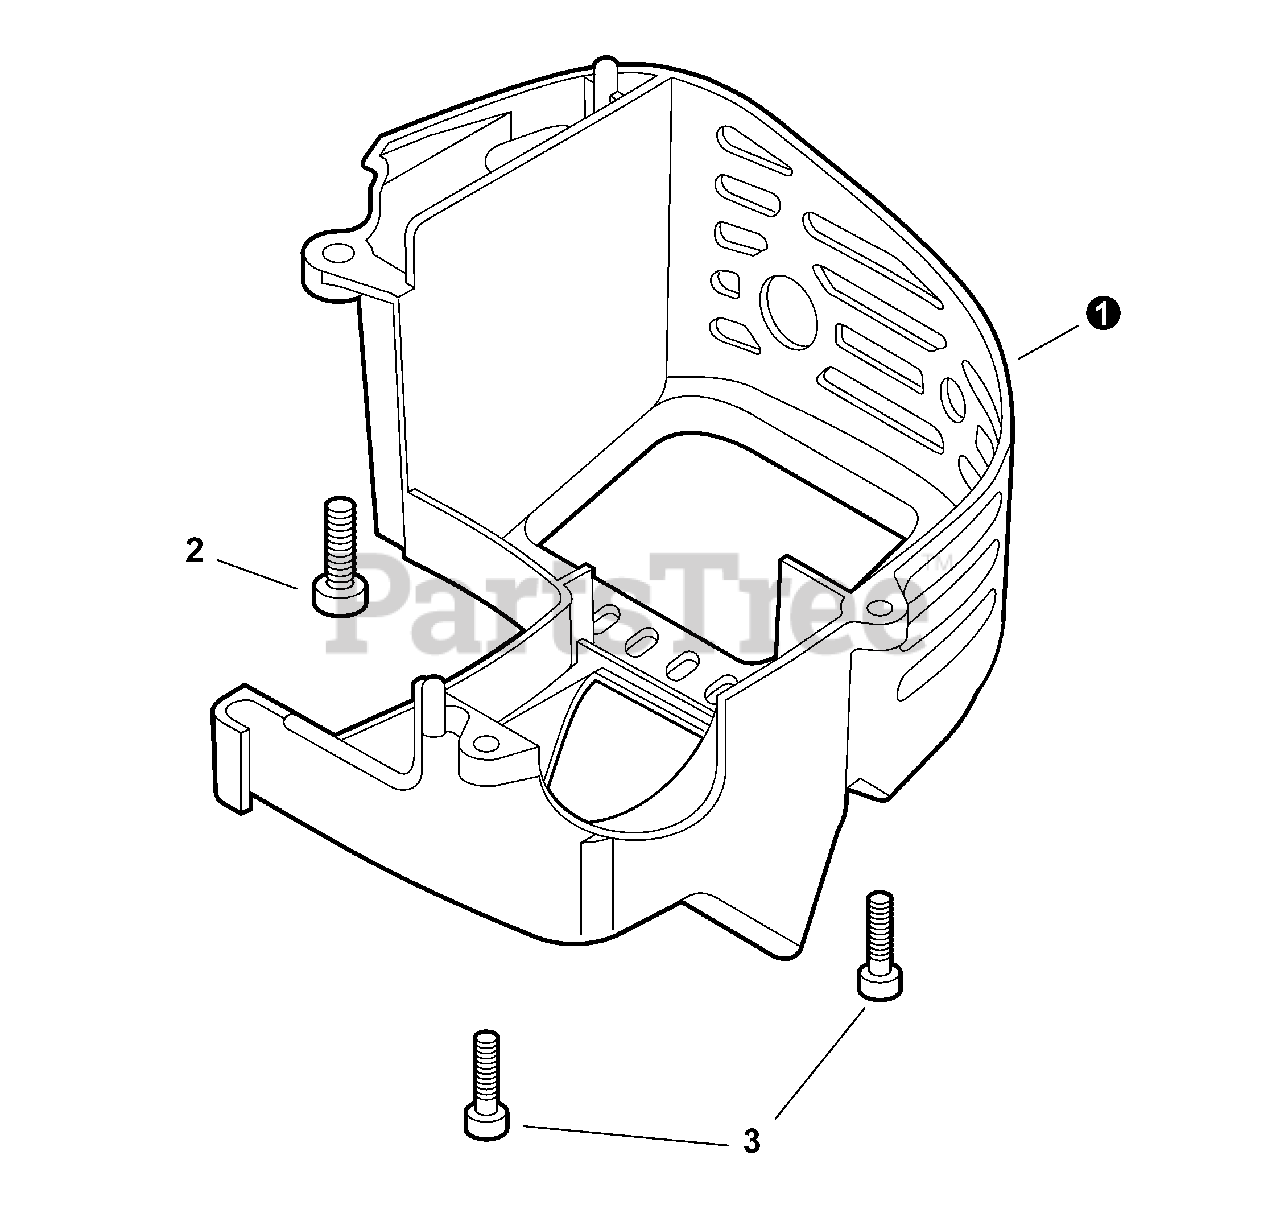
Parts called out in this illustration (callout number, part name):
1	COVER, ENGINE
2	BOLT, TORX 5×16
3	BOLT, TORX 4×16
